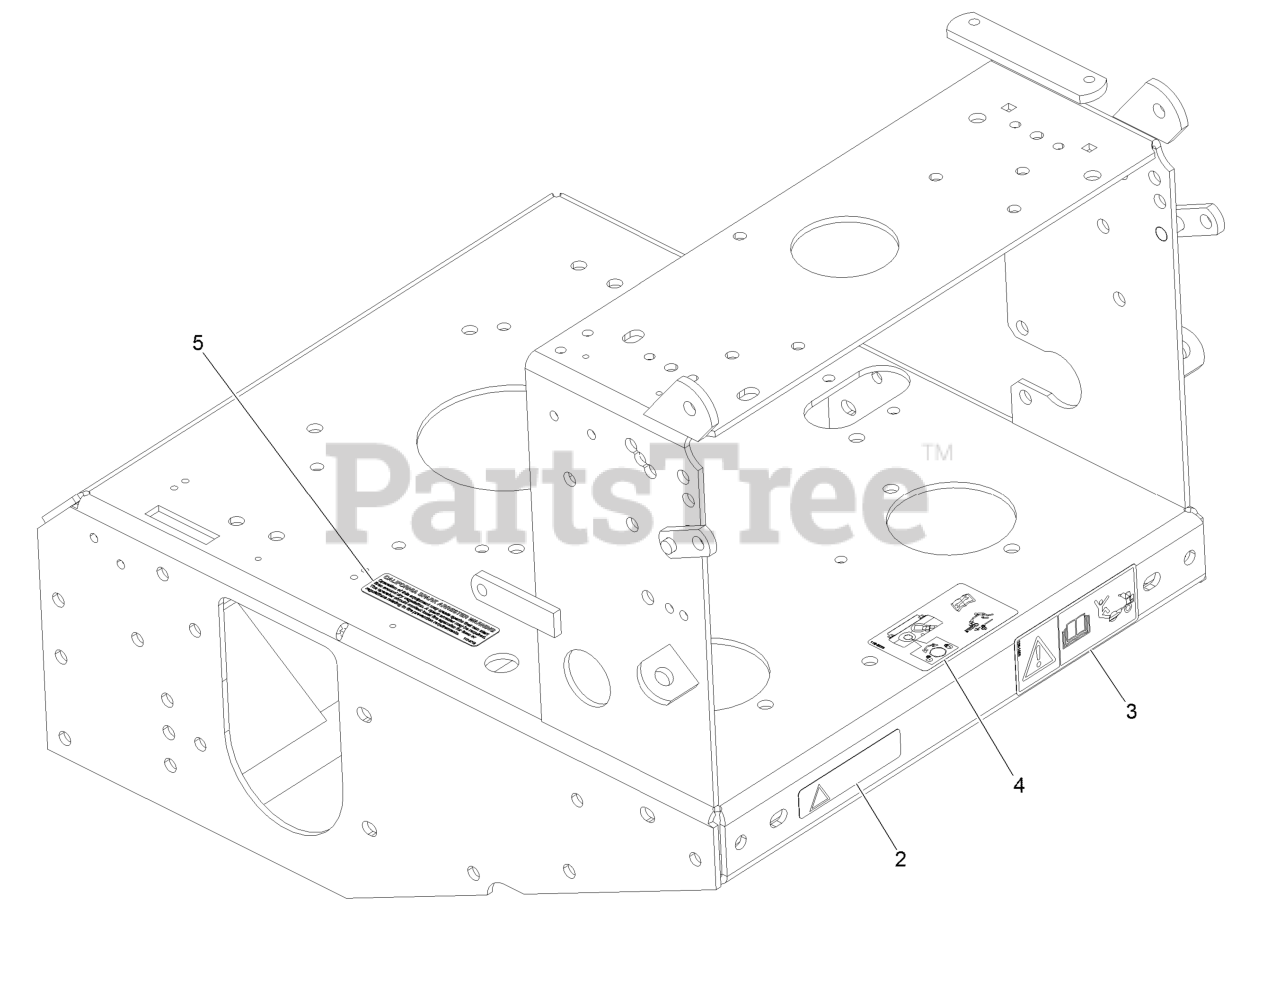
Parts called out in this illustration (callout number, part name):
2	Decal-Warning
3	Decal-Warning, Sulky
4	Decal-Drive Release
5	Decal-Arrester, Spark
